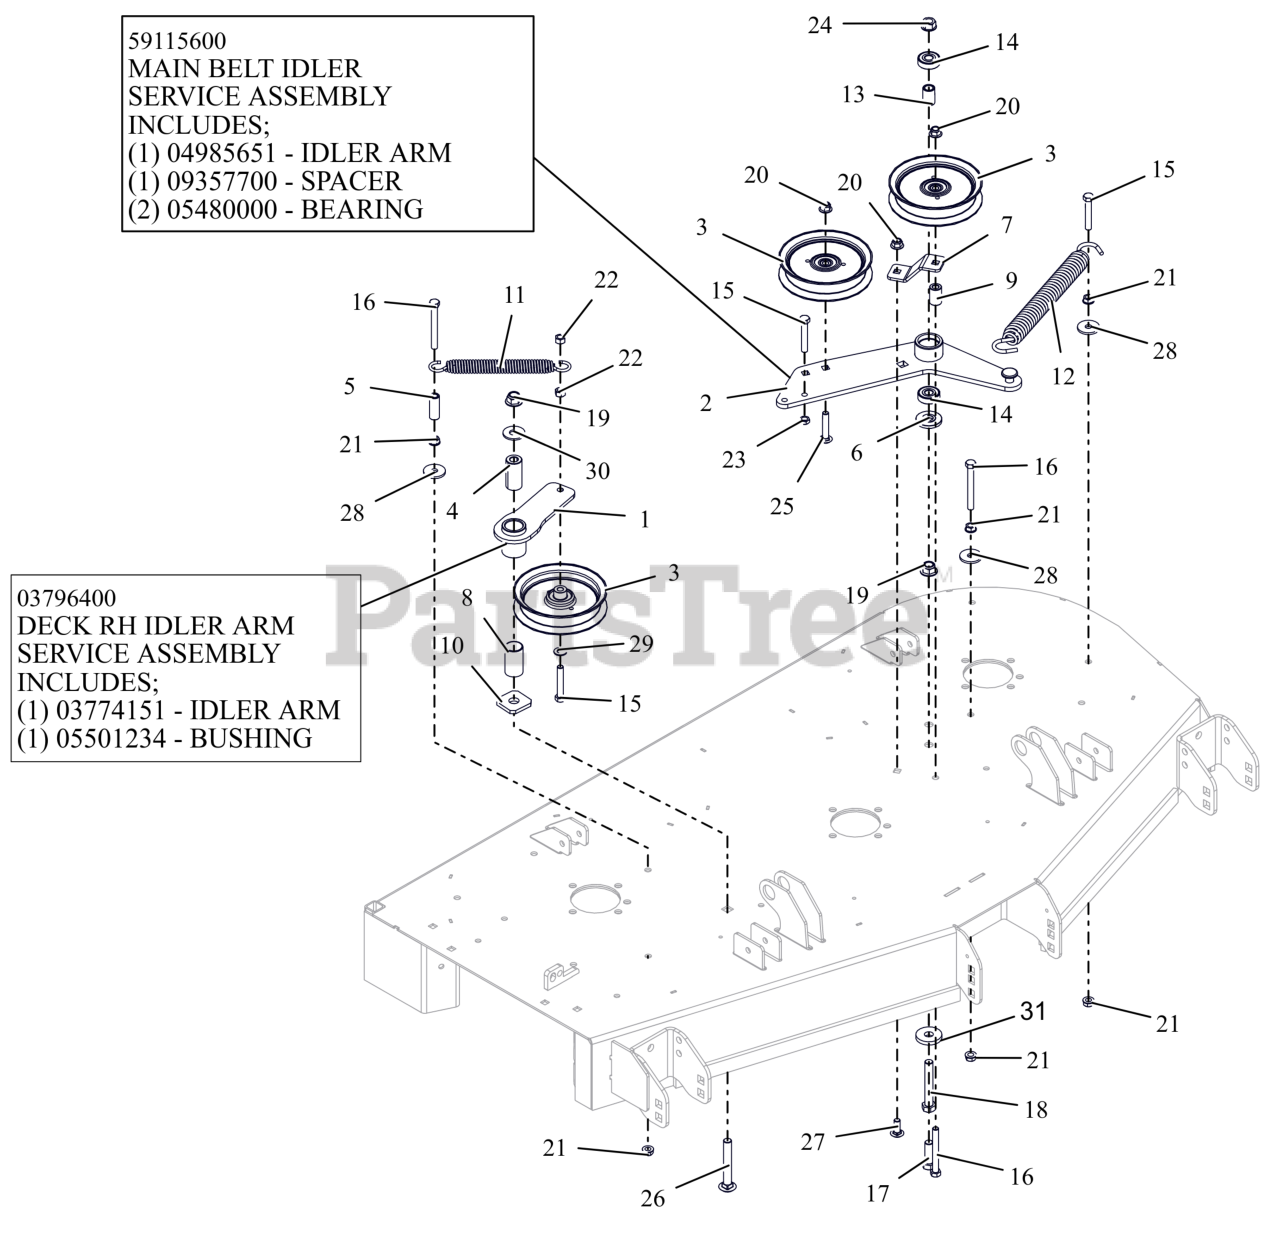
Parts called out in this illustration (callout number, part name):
1	WMT, IDLER ARM - BLACK
1	ASM, IDLER ARM (DECK)
2	DECK PTO IDLER ARM WLDMT - BLK
2	ASSEMBLY, MAIN BELT IDLER
3	IDLER, FLAT 5.00"
4	BSHG, SPCR .502X.997X2.03 PM
5	SPACER, .375IDX.625ODX1.66 PM
6	SPACER, IDLER ARM
7	PTO FIXED IDLER MTG BRKT-ORG
8	BSHG, 1.00X1.125X1.937
9	BUSHING, SLV .380X.750X1.190
10	WSHR-FLT .640X1.75X.250
11	SPRING, EXTENSION
12	SPRING, EXTENSION
13	SPACER .510 X .75 X 1.1485
14	BRG-BALL .500X1.38X.437
15	BLT,HEX .38-16X2.25 G5 ZCC
16	BLT, HEX .38-16X3.25 G5 ZCC
17	BLT,HEX .50-13X1.50 G5 ZCC
18	BLT,HEX .50-13X3.25 G5 ZCC
19	NUT,NYL-FLG .50-13 GF ZCC
20	NUT,NYL-FLG .38-16 GF ZCC
21	NUT, SPNLK-FLG .38-16 G5 ZCC
22	NUT-LK-CTR .38-16 ZC120
23	NUT-JAM .375-16 G2 ZCC
24	NUT-LK-CTR-FLG .500-13 GG ZCC
25	BLT,RHSSN.375-16X2.00 G5 ZCC
26	BLT, RHSN .50-13X3.50 G5 ZCC
27	BLT,RHSSN .38-16X1.00 G5 ZCC
28	WSHR,FLT .406X1.375X.135 ZCC
29	WSHR,FLT .406X.812X.065 ZCC
30	WSHR,FLT .563X1.375X.109 ZCC
31	WSHR-FL-STL 0.557X1.625X0.25 ZCC
